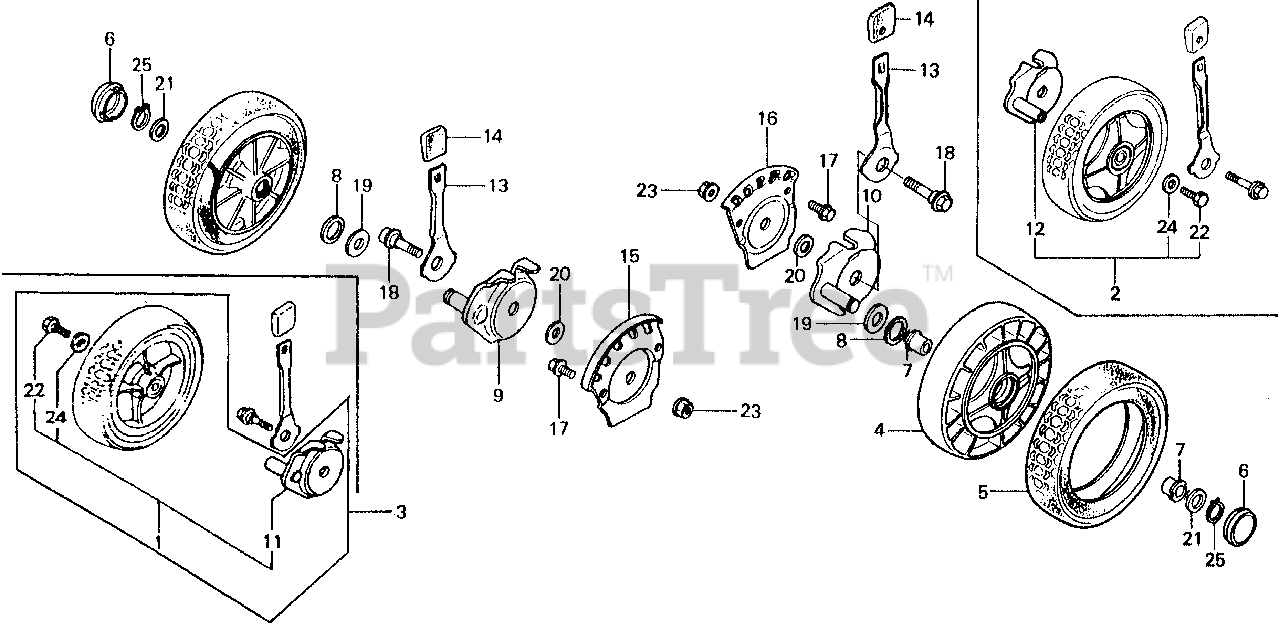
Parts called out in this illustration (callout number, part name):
1	ARM, R. KIT ADJUSTER
2	ARM KIT, L. ADJUSTER (N/A: SEE COMPONENTS)
3	WHEEL KIT, FR.
4	WHEEL KIT, FR.
5	TIRE, FR. (7INCH)
6	CAP, WHEEL
7	BUSH, WHEEL
8	FELT, WHEEL SHAFT
9	ARM, R. KIT ADJUSTER
10	ARM, L. FR. ADJUSTER
11	ARM, R. RR. ADJUSTING
12	ARM, L. RR. ADJUSTING
13	PLATE, FR. ADJUSTING
14	GRIP, ADJUSTER
15	PANEL, R. FR. ADJUSTING
16	PANEL, L. FR. ADJUSTING
17	BOLT, FLANGE (6X12) (CT200)
18	BOLT, FR. ADJUSTER ARM (NOT AVAILABLE)
19	WASHER (15MM)
20	WASHER (10MM)
21	WASHER, THRUST (15MM)
22	BOLT, HEX. (8X12)
23	NUT, FLANGE (10MM)
24	WASHER, PLAIN (8MM)
25	CIRCLIP (OUTER) (15MM)
